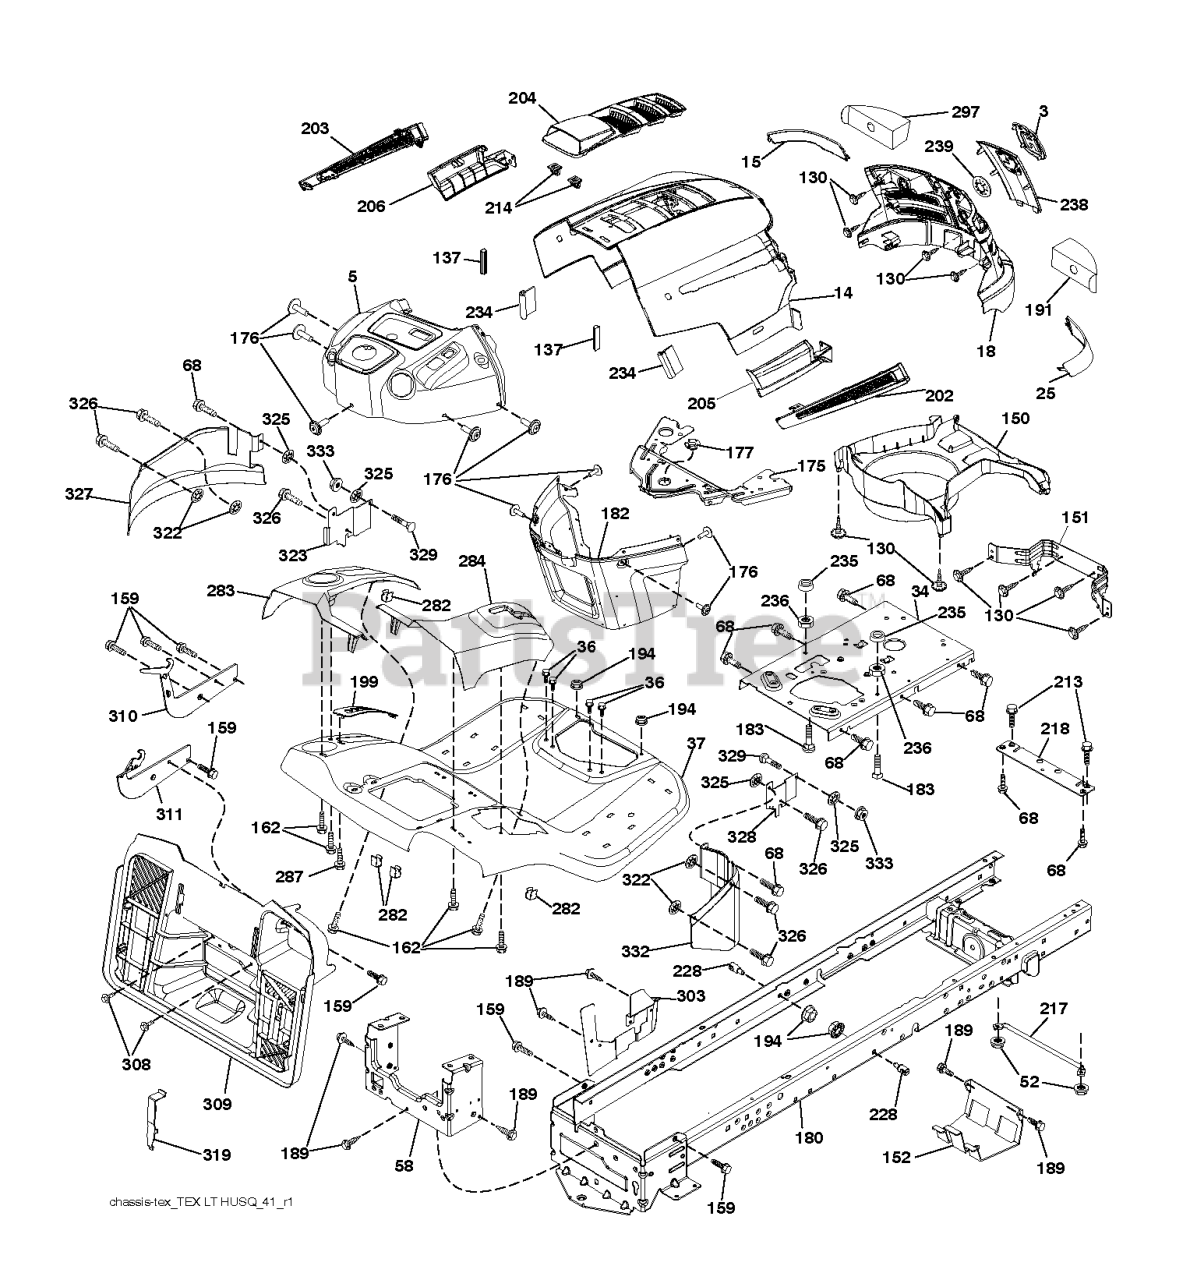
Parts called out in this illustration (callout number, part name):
3	RP LOGO
5	DASH
14	HOOD.HUSQVARNA.LT.ORANGE
15	LENS.HUSQVARNA LT.LH
18	GRILLE.SVC.HUSQVARNA.LT.GREY
25	LENS.HUSQVARNA LT.RH
34	PLATE.ENGINE.WELDED.CHASSIS
36	SCREW 5/16"
37	FENDER.TEX.SRD.CRD.FRN.GUARDS
52	LOCKNUT
58	DRAWBAR UPPER 2PC SMALL FENDER
68	Screw 5/16-18 x 1/2 Hex, Self Tapping 5/16-18 x 1/2
130	SCREW.#10 X 0.750.BOS
137	BUMPER DASH
151	BRACKET PIVOT
152	SHIELD.BROWNING.W/TEX
159	SCREW, 3/8-16X3/4
162	SCREW.HI-LO.CONSOLE
175	CROSSMEMBER
176	SCREW.#10-24X5/8.RN.QU
177	BUSHING STEERING
180	CHASSIS.WLDMNT.14GA.2PC.18".TI
182	DASH.LOWER.PREDATOR LT
183	BOLT.5/16-18X1-1/4 FULL THD
189	SCREW
191	INSERT.REFLECTIVE.RH.
194	NUT LOCK HEX FLANGE 5/16-18
199	PLATE DECK LIFT
202	VENT SIDE HOOD RH
203	VENT SIDE HOOD LH
204	VENT TOP HOOD
205	SKIRT SIDE RH
206	SKIRT SIDE LH
213	BOLT
214	CLIP.RETAINER.TINNER.
217	ROD.PIVOT.HOOD
218	X-PIECE.HOOD.STOP.NON/
228	STUD.FASTNER.W/ANTI-ROTATE
234	BUMPER.HOOD.TEX.HUSQVARNA
235	SPACER FENDER
236	NUT.CENTERLOCK.5/16-
238	TRIM
282	CLIP.RETAINER.CONSOLE.LT.HUSQ
283	CONSL.DECKLIFT.LH.SRD.TEX.CRD
284	CONSL.SHIFT.GEAR.RH.SRD.GREY
287	SCREW 1/4X20
297	INSERT REFLECTIVE
303	SHIELD CHASSIS LEFT
308	BOLT.5/16-18UNCX3/4 W/SEMS.BLK
309	BACKPLATE.BAGGER.V2.SRD
310	LH.ADJUST.HANGER.BRACKET.ASM
311	RH.ADJUST.HANGER.BRACKET.ASM
319	BRACKET.ACTUATOR.BAGGER.SRD
322	PALNUT 1/4
323	GUARD FRONT LEFT
325	WASHER 5/16"
326	SCREW 14-20 X 5/8
327	GUARD LEFT
328	GUARD FRONT RIGHT
329	BOLT
332	GUARD RIGHT
333	NUT.71038.31-18.HEX.NYLOCK
